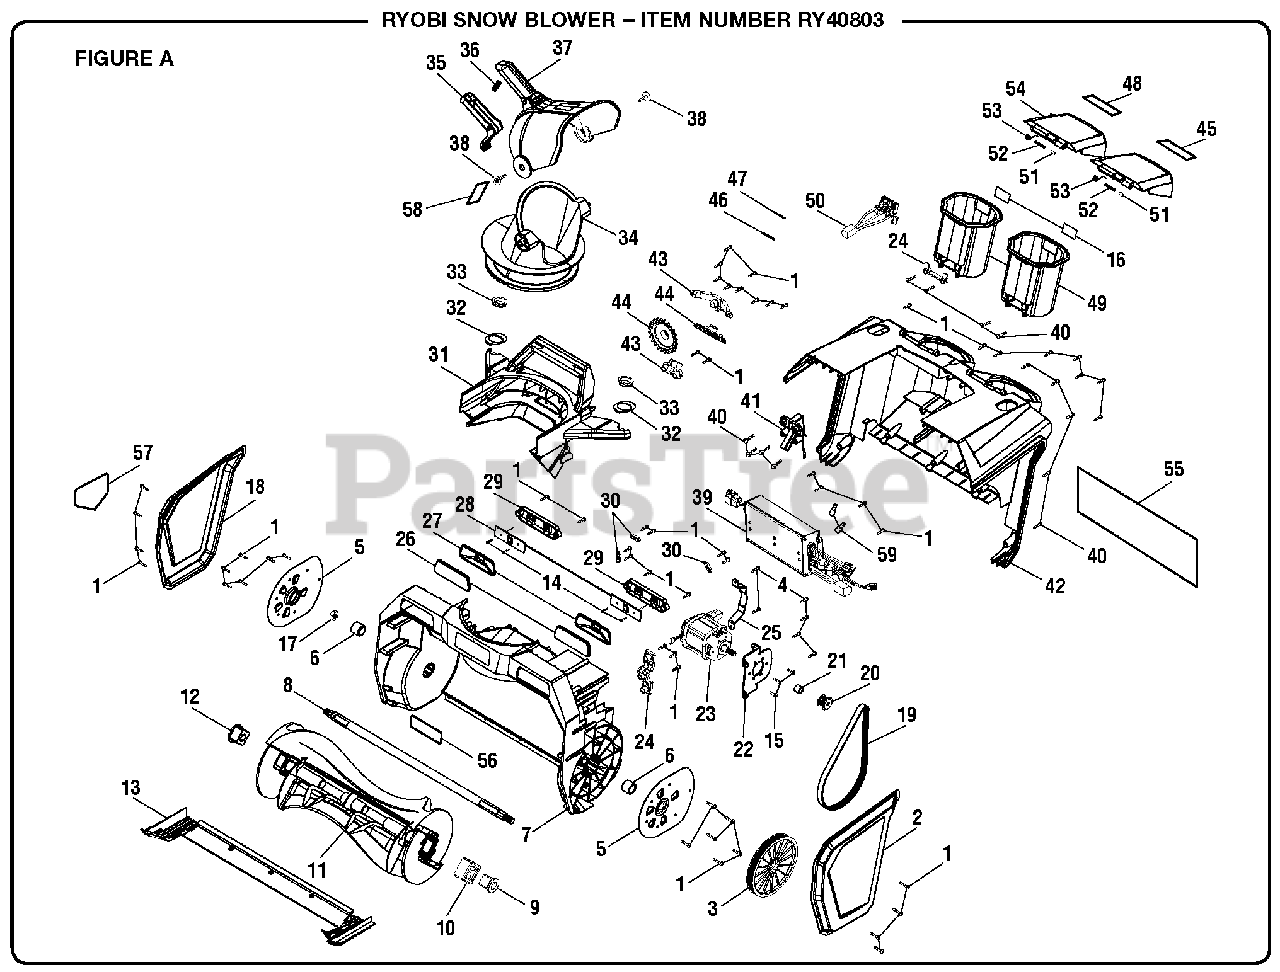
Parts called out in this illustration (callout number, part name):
1	Screw (4 x 18 mm, T15 Torx Pan Hd.)
2	Left Side Cover
4	Screw (M4-18 x 30 mm, T15 Torx Soc. Hd.)
5	Bearing Plate w/Bearing Assembly
7	Front Housing Assembly
8	Auger Shaft
9	Left Drive Block
10	Connect Plate
12	Right Drive Block
13	Scraper Blade Assembly
14	Screw (M3-24 x 8 mm, Pan Hd.)
15	Screw w/Washer (M5 x 8 mm, Pan Hd.)
16	Battery Temperature Label
17	Hex Nut (M12)
18	Right Cover Assembly
19	V-Belt (Type 5EPJ568)
20	Drive Pulley
21	Motor Bushing
22	Motor Locating Plate
24	Motor Support & Terminal Holder Assembly
25	Motor Plate
26	Headlight Lens
27	Reflector
28	LED Light Plate Assembly (Set of 2)
29	Fixing Plate (LED Lens)
30	Cord Clamp
31	Carry Handle
33	Rubber Bushing
35	Nozzle Adjustment Handle
36	Compression Spring
37	Chute Nozzle Assembly
38	Screw w/Washer (M4-18 x 10 mm, T20 Torx Pan Hd.)
39	Brushless Motor Controller
40	Screw (M4 x 20 mm, T20 Torx Pan Hd.)
41	Fixing Plate (Chute Rod)
42	Rear Housing Assembly
43	Gear Support Assembly
44	Gear Assembly
45	On-Board Storage Label
46	Washer (ID 17.5 x OD24 x 1t)
48	In-Use Label
49	Battery Carriage
50	Battery Holder Assembly
52	Compression Spring
53	Torsion Spring
54	Battery Cover Assembly
55	Danger/Data Label
56	Front Logo Label
57	CPSC Label
58	Chute Icon Label
59	Wire Connector
